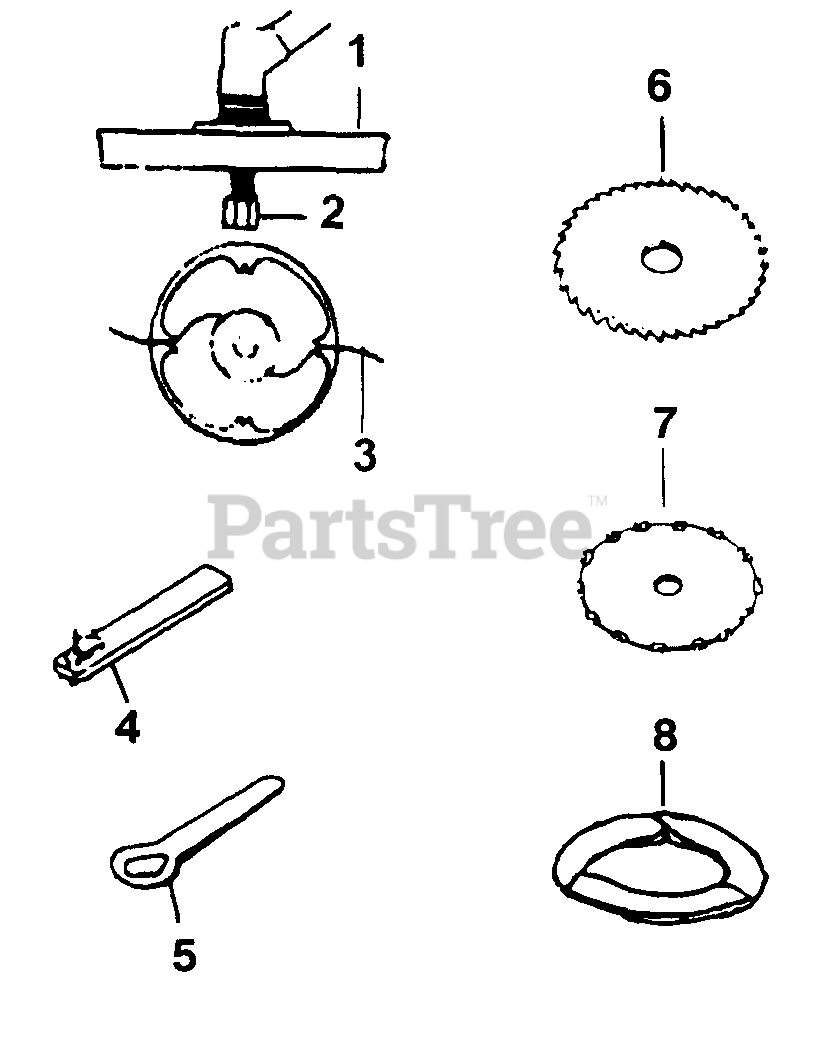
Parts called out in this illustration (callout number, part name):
1	FIXED LINE HEAD
2	ARBOR BOLT
3	GREEN LINE .105 X 20"
4	ROTOR PULLER
5	FLYWHEEL HOLDER
6	SAW BLADE
7	XRT BLADE
8	COVER, BLADE
